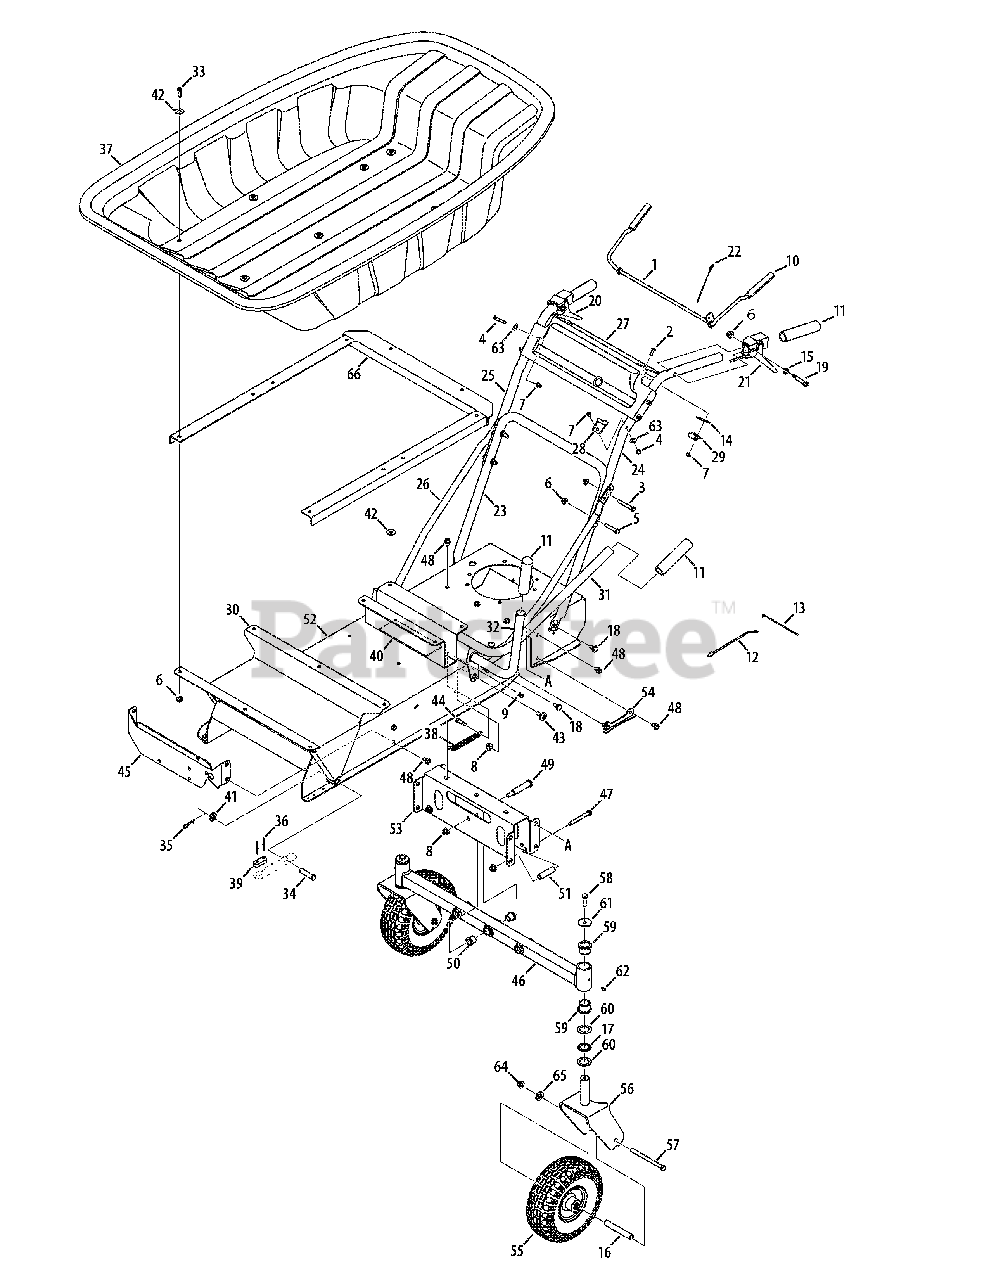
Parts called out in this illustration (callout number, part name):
1	Brake Bail Assembly
2	Screw, 1/4-20 x 0.750
3	Hex Head Screw, 5/16-18 x 2.25
4	Hex Head Screw, 1/4-20 x 1.50
5	Hex Head Screw, 5/16-18 x 1.75
6	Flangelock Nut, 5/16-18
7	Flangelock Nut, 1/4-20
8	Flangelock Nut, 3/8-16
9	Cap Lock Nut, 1/4-20
10	Reverse Handle Grip
11	Grip, 1.0 ID x 5.0 LG
12	Cable Tie, 7.5 LG, Push Mount
13	Cable Tie, 8.5 LG
14	Damper Pad
15	Washer, Lock, 3/8
16	Spacer, .375 x .625 x 4.05
17	Thrust Bearing Needle, 1.00 x 1.562
18	Shield Screw, .435 x .178 - 5/16 x .56
19	Socket Head Screw, 5/16-18 x .375
20	Forward Cable
21	Reverse Cable
22	Brake Release Cable
24	Upper Handle, LH
25	Upper Handle, RH
26	Handle Adjuster Brace Tube
28	Cable Mounting Bracket, LH
29	Retainer Bracket, RH
30	Pivot Bed Bracket Assembly
31	Bed Handle Assembly
32	Lock Bracket Assembly
33	Screw, 5/16-18 x 1.00
34	Clevis Pin, .500 x 2.00
35	Click Pin, .092 x 1.64 LG
36	Rivet, .125 DIA x .625
38	Extension Spring, .60 OD x 6.44 LG
39	Bumper Pad
40	Rubber Pad
41	Washer, Flat, .510 x 1.000 x .125
42	Washer, Flat, .344 x 1.00 x .063
43	Screw, Shoulder, 3/8-16 x .625 x .145
44	Screw, Shoulder, 1/4-20 x .31 x .75
45	Transmission Support Bracket
46	Front Axle Assembly
47	Hex Head Screw, 3/8-16 x 3.00
48	Screw, 5/16-18 x 0.625
49	Shoulder Bolt, 3/8-16 x .625 x 2.515
50	Bronze Flange Bearing, .630 ID
51	Spacer Tube, .385 x .625 x 2.250
53	Pivot Mount Bracket
54	Frame Brace Bracket
55	Wheel Assembly, 10.0 x 3.5
56	10" Wheel Caster Assembly
57	Hex Head Screw, 3/8-16 x 5.00
58	Hex Head Screw, 3/8-24 x 1.25
59	Flange, Bearing, 1.00 ID x 1.246 OD
60	Washer, Flat, 1.03 x 1.62 x .03
61	Washer, Flat, .385 x 1.5 x .075
62	Drive Lube Fitting,3/16
63	Washer, Flat, .28 x .74 x .063
64	Nut, Jamlock, 3/8-16
65	Washer, Flat, .375 x .738 x .063
66	Bed Frame Assembly
